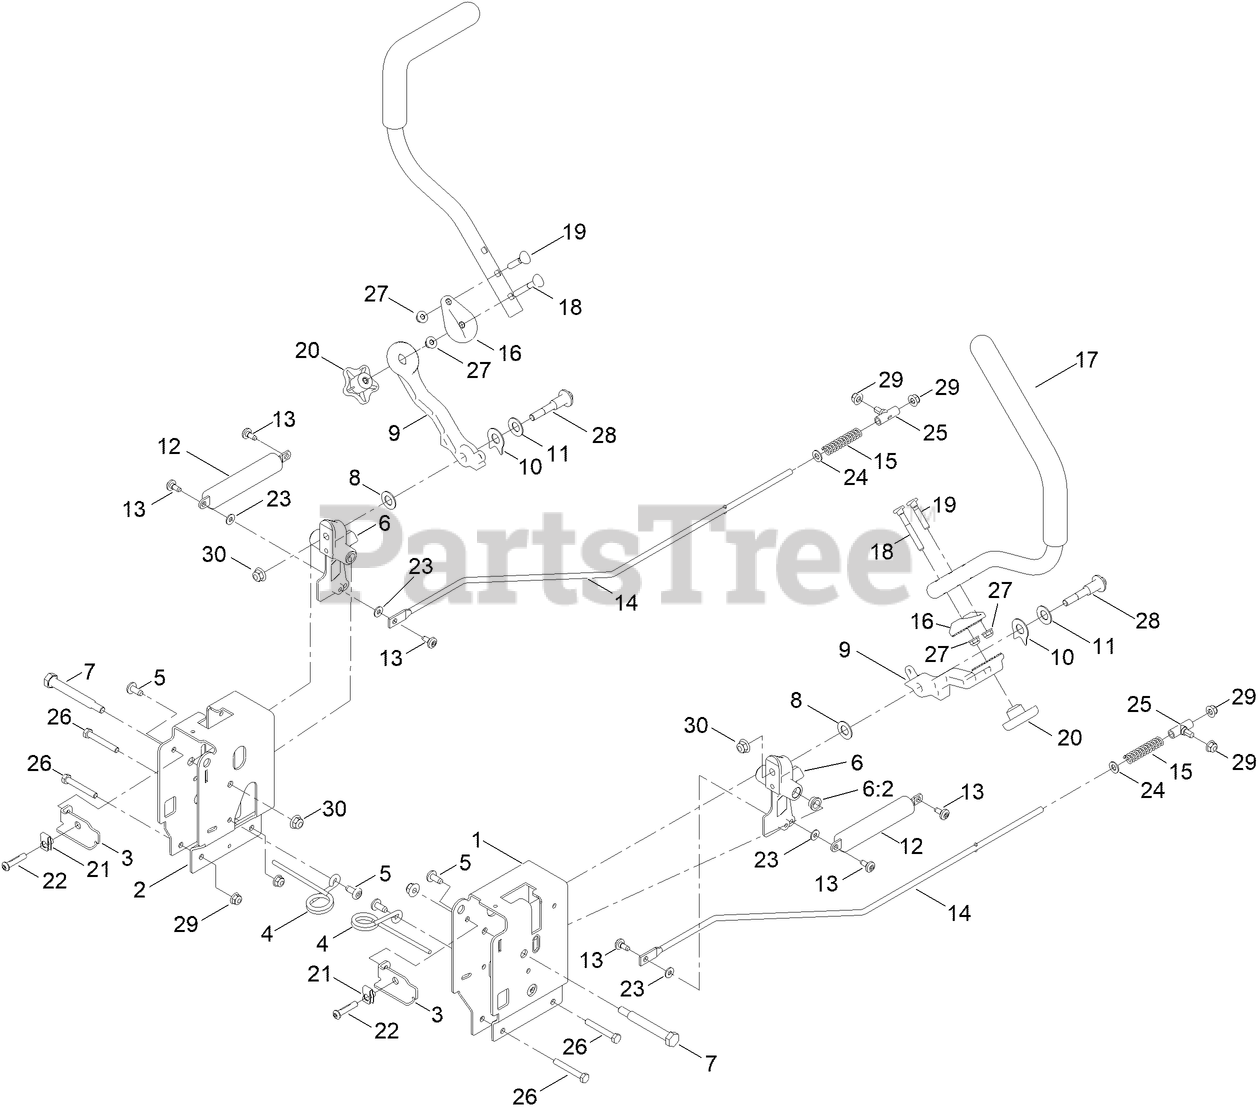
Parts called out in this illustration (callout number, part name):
1	CONTROL BOX - LH G7
2	CONTROL BOX - RH G7
3	ADJUSTMENT PLATE-CONTROL BOX
4	SPRING-TORSION
6	PIVOT ARM ASM
6:2	BUSHING-FLANGE
7	BOLT-PIVOT
8	WASHER-NYLON
9	ARM-CONTROL, 32 TEETH
10	SPACER, ANTI-ROTATION
11	WASHER-BELLEVILLE
12	DAMPER-NON CAVITATING
13	SCREW-SHOULDER
14	ROD - HYDRO, LH
15	SPRING-COMPRESSION
16	DISC-ADJUSTMENT HANDLE, 32 TEETH
17	HANDLE-CONTROL
18	SCREW-HANDLE
19	SCREW-HANDLE
20	KNOB-HANDLE
22	SCREW-HSBH
23	WASHER
24	WASHER-PLAIN
25	MOUNT-ROD, HYDRO
26	SCREW-HH
27	NUT-HF
28	BOLT-PIVOT
29	NUT-HF, NI
30	NUT-HF, NI
